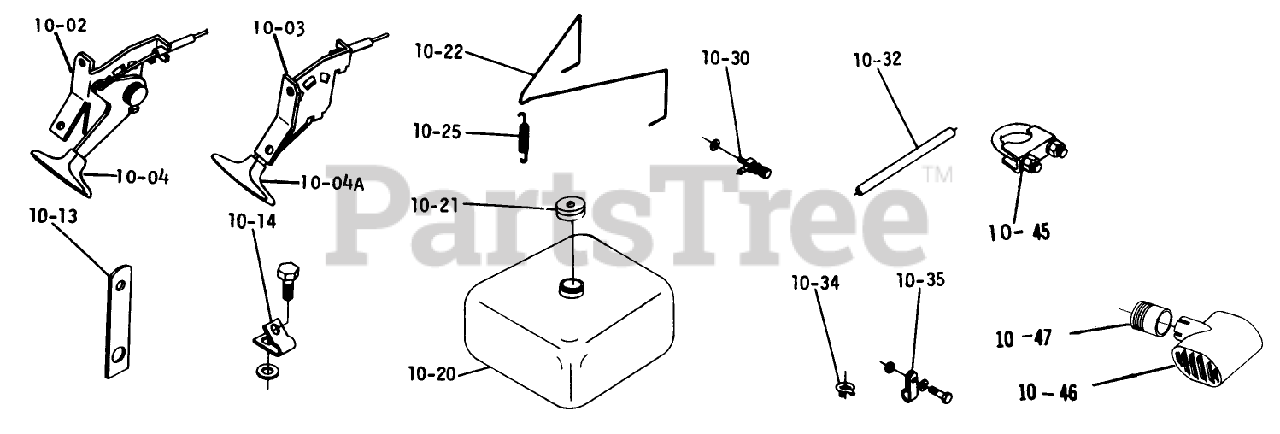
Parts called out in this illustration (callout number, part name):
10-02	Choke Control
10-03	THROTTLE CONTROL
10-04	KNOB-CHOKE
10-04A	KNOB-THROTTLE
10-13	Strap
10-14	THROTTLE CONTROL CLP
10-20	ASSY-FUEL TANK
10-21	Cap
10-22	HOLD DOWN WIRE
10-25	CLUTCH SPRING
10-30	VALVE-FUEL
10-32	Hose-Fuel
10-34	Clamp
10-35	CLAMP-HOSE
10-45	ASSY-MUFFLER CLAMP
10-46	MUFFLER
10-47	Nipple
